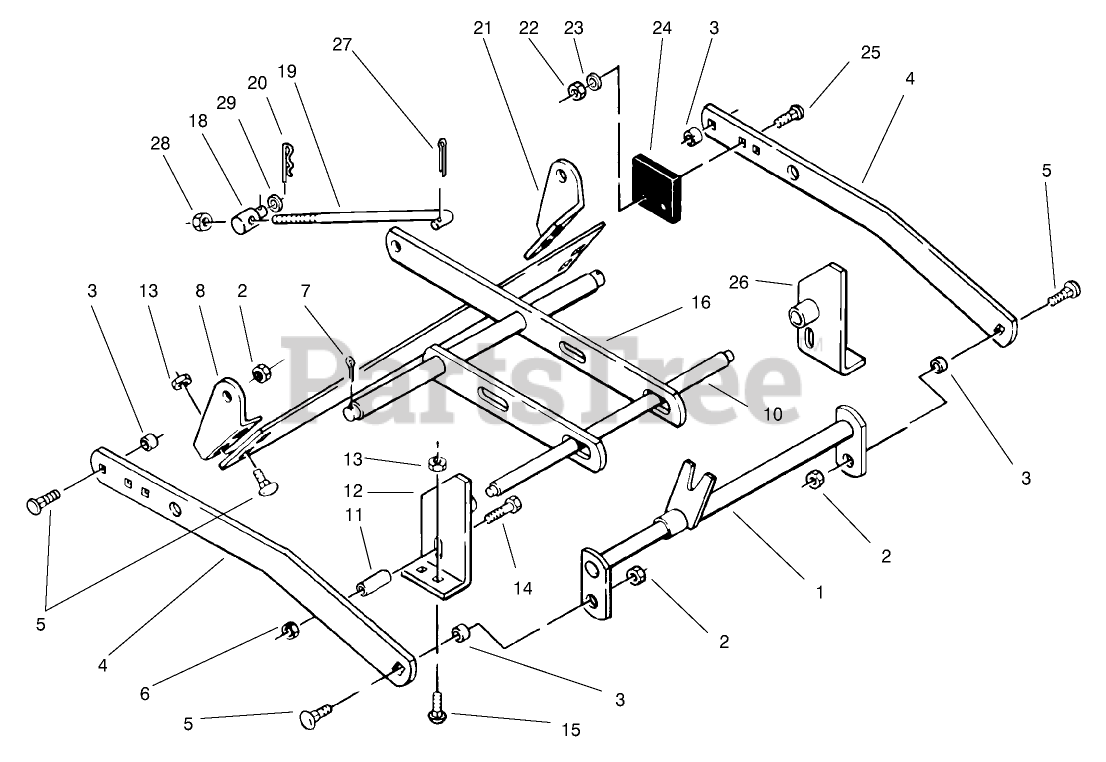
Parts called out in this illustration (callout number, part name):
1	WA HITCH (RED)
2	LOCKNUT-FLANGE
3	SPACER
4	BAR DRAFT (RED)
5	BOLT-CARR
6	NUT-LOCK, NI
7	PIN-COTTER
8	DCK BRKT R (RED)
10	SHAFT FRONT (RED)
11	SPACER
12	WA-RH FRT DK BRK (RED)
13	NUT-LOCK, NI
14	BOLT-CARR
15	BOLT-CARR
16	WA-LEVELER BAR (RED)
18	TRUNNION
19	LIFT ROD
20	PIN-HAIR
21	DCK BRKT L (RED)
22	NUT-LOCK, NI
23	WASHER-FLAT
24	BUMPER
25	SCREW-CARR
26	WA-LH FRT DK BRK (RED)
27	PIN-COTTER
28	NUT-LOCK, NI
29	WASHER-FLAT
